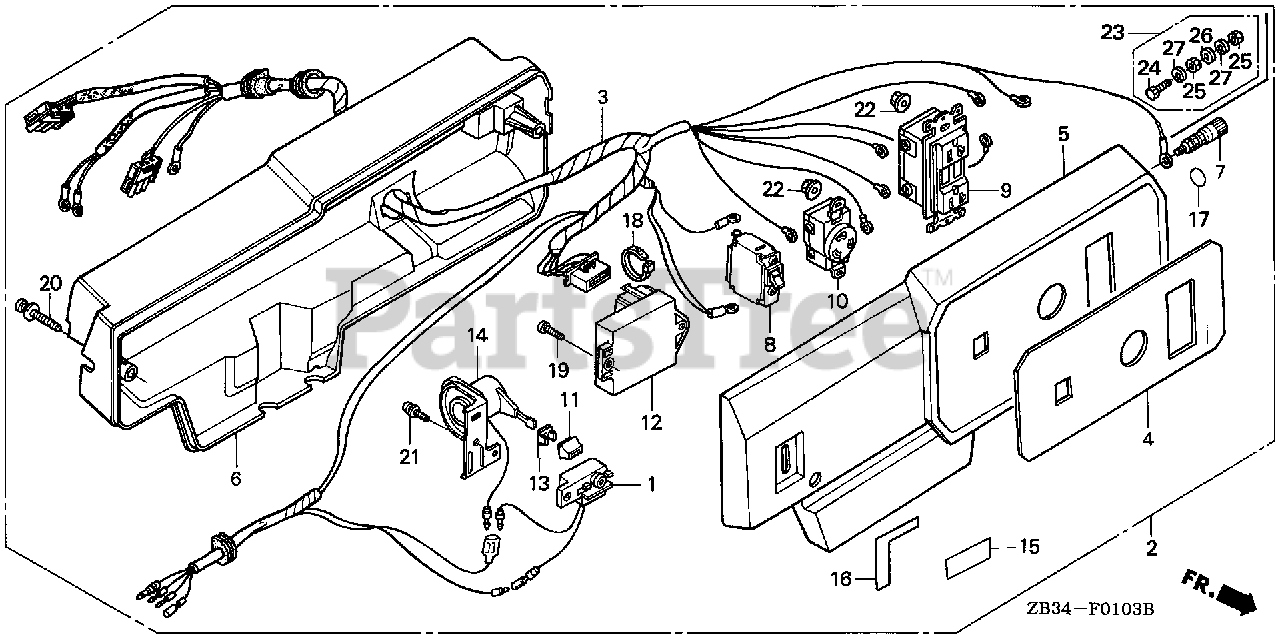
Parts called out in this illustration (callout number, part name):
2	BOX ASSY., CONTROL *R280* (POWER RED) (NOT AVAILABLE)
3	WIRE HARNESS ASSY.
4	MARK, SWITCH PANEL
5	PANEL, CONTROL *R280* (POWER RED)
6	CASE, CONTROL *R280* (POWER RED)
8	BREAKER, CIRCUIT (20A)
9	RECEPTACLE (20A/125V)
10	RECEPTACLE (20A/125V)
11	KNOB, PETCOCK LEVER
12	REGULATOR UNIT, AUTOMATIC VOLTAGE
14	SWITCH ASSY., ENGINE
15	MARK, OIL ALERT (ENGLISH)
16	MARK, ENGINE SWITCH INDICATION
17	MARK, GROUND
19	SCREW, PAN (5X8)
20	SCREW-WASHER (6X45)
21	SCREW-WASHER (4X8)
22	NUT, FLANGE (4MM)
23	TERMINAL SET, GROUND
24	BOLT, HEX. (6X28)
25	NUT, HEX. (6MM)
26	WASHER, PLAIN (6MM)
27	WASHER, SPRING (6MM)
